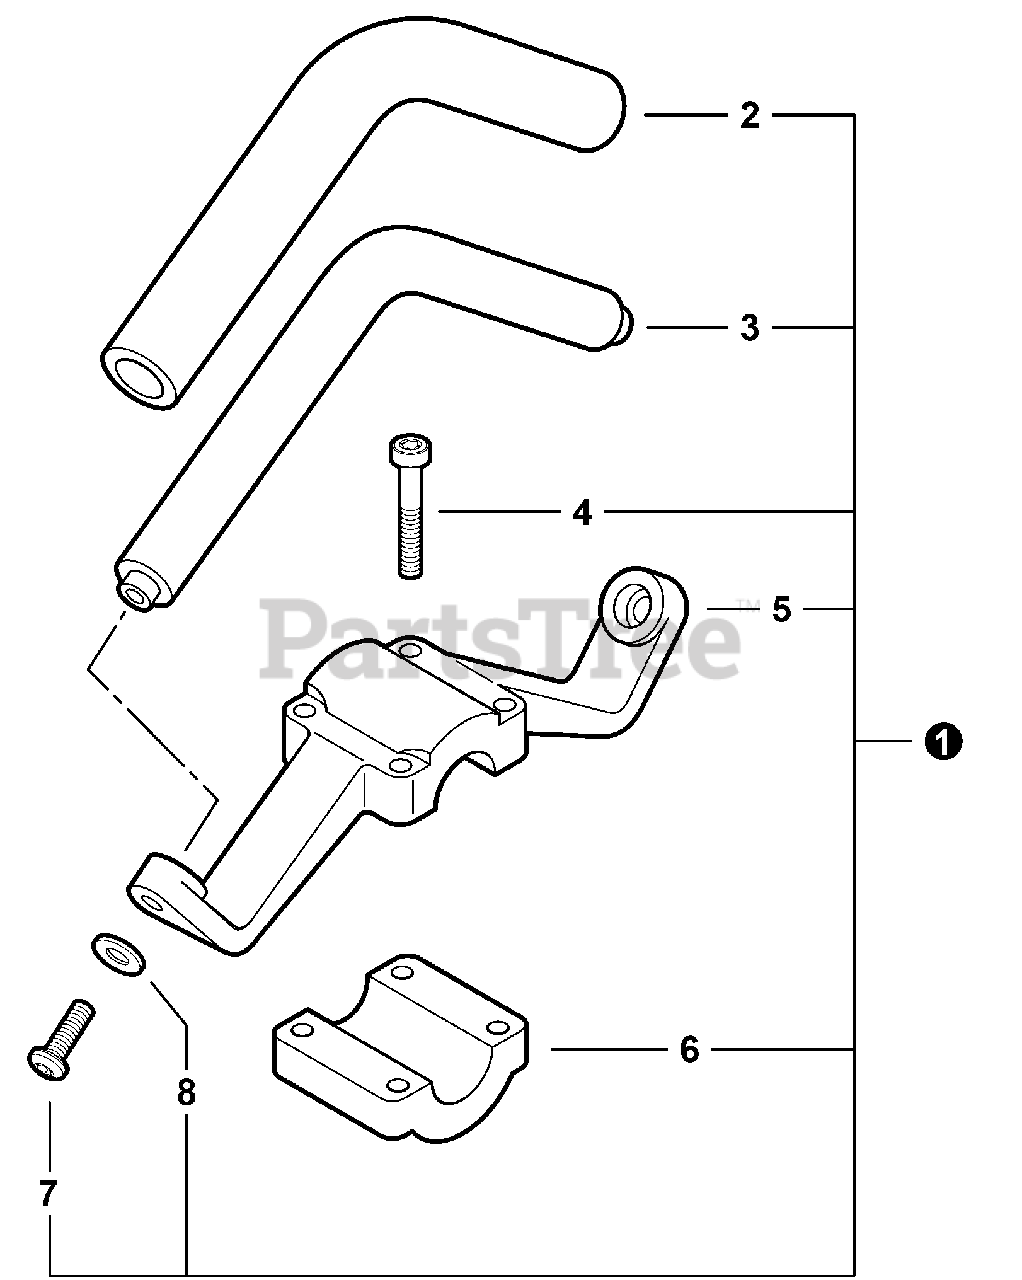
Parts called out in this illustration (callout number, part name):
1	FRONT HANDLE ASSY
2	GRIP, HANDLE
3	HANDLE - FRONT
4	SCREW - 5X30
5	BRACKET, HANDLE - UPPER
6	BRACKET, HANDLE - LOWER
7	SCREW - 5X20
8	WASHER - 5
